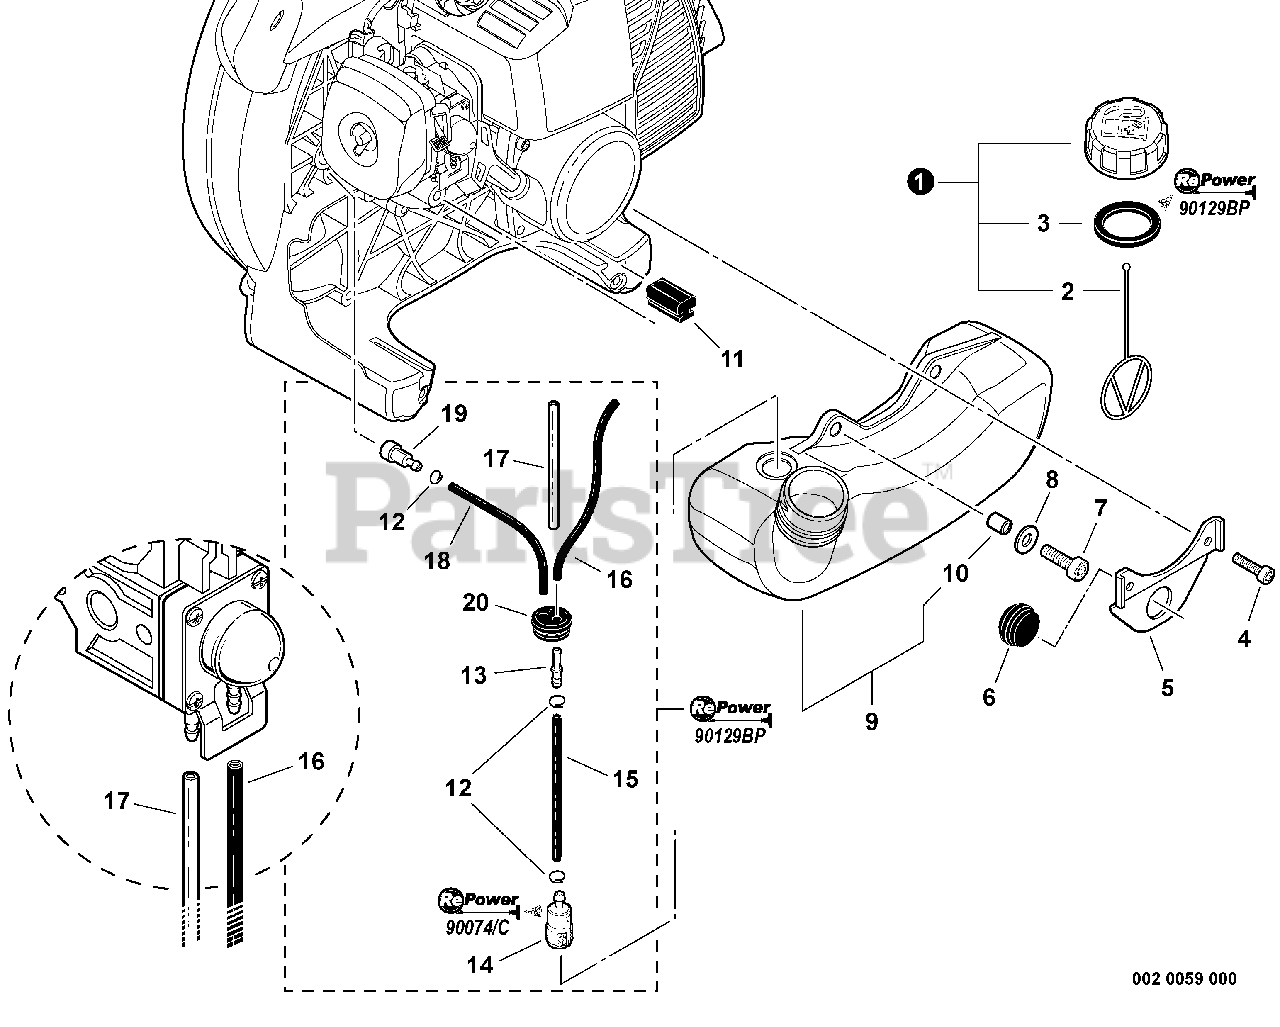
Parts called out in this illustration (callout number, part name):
1	CAP ASSY, FUEL
2	CONNECTOR, CAP L= 100 MM
3	GASKET, FUEL CAP
4	BOLT, TORX 4×16
5	BRACKET, FUEL TANK
6	CUSHION
7	BOLT, TORX 5×16
8	WASHER 5.5×12×0.8
9	TANK ASSY, FUEL
10	SPACER 6.2×7.8×6
12	CLIP Ø6
13	CONNECTOR, PIPE Ø5ר3.5
14	FILTER, FUEL
15	PIPE, FUEL 3×5×130 BLACK
16	PIPE, FUEL 3×5×78 BLACK
17	PIPE, FUEL 3×6×85 CLEAR
18	PIPE, FUEL 3×5×80 BLACK
19	VENT ASSY
20	GROMMET, FUEL Ø5
21	FUEL SYSTEM KIT
22	TUNE-UP KIT - REPOWER
